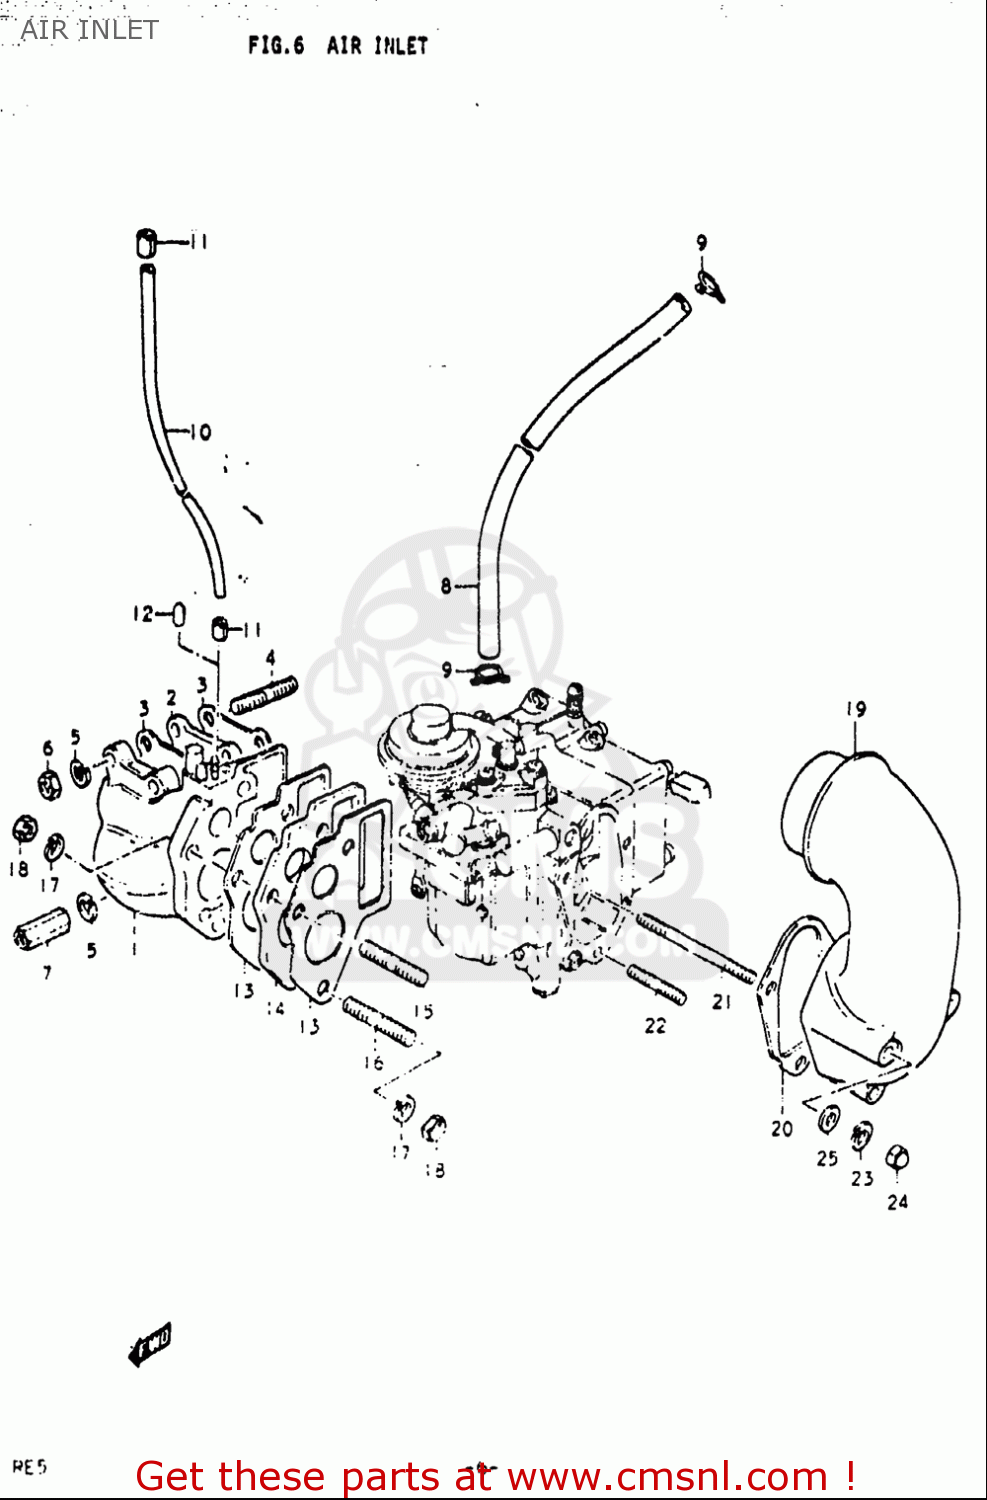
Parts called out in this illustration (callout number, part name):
4	STUD 8X25
5	WASHER,LOCK
6	NUT
9	CLIP
10	HOSE(3X5X600)
11	CLIP
15	STUD 8X1.25X36
16	STUD 8X30
17	WASHER,LOCK
18	NUT
22	BOLT, STUD
23	WASHER,LOCK
24	NUT
25	WASHER
